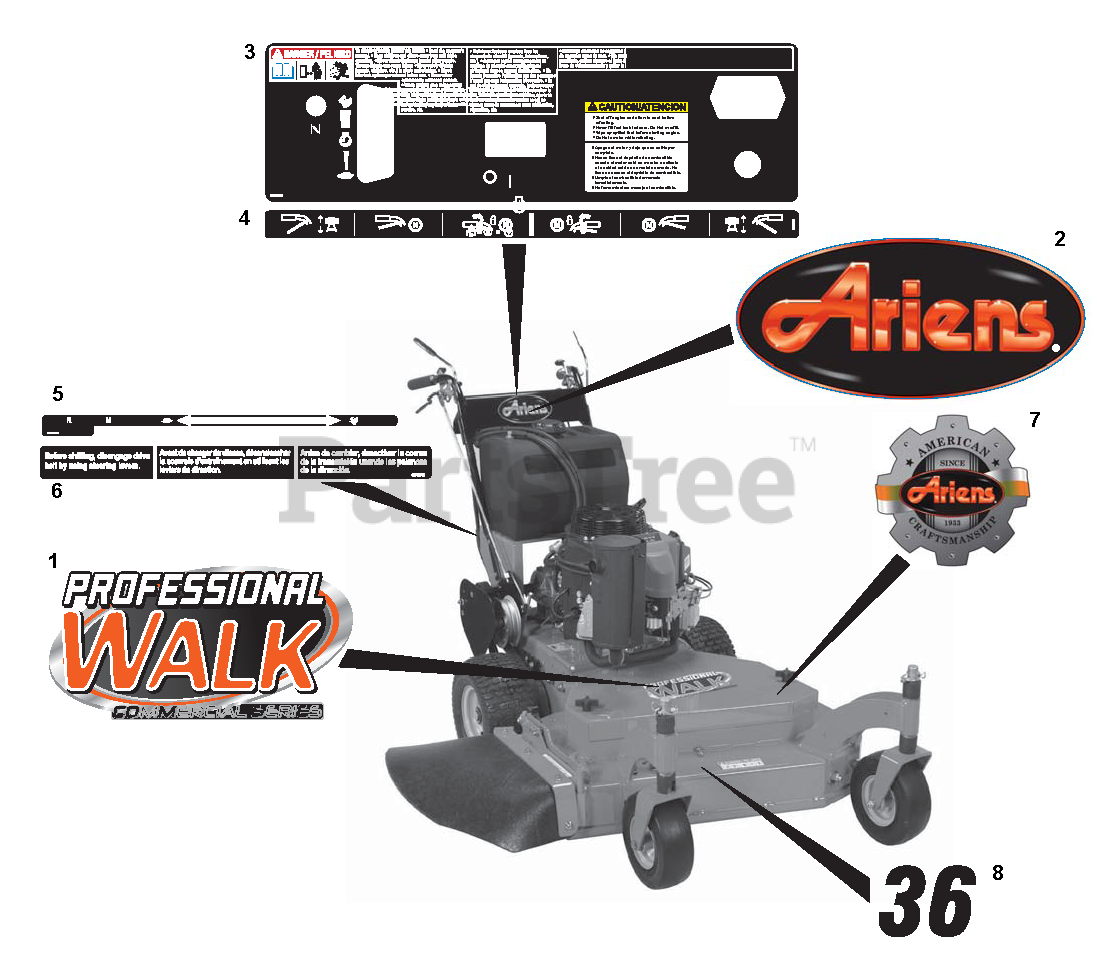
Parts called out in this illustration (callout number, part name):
1	DECAL, ARIENS WALK
2	DECAL, ARIENS JEWEL
3	DECAL, CONSOLE ACAO GWK 2011
4	DECAL, STEER LVRS (GEAR)
5	DECAL-SHIFT LEVER
6	DECAL - DECLUTCH - GEAR
7	Decal, Ariens Heritage, Large
8	DECAL, DECK SIZE, 36"
